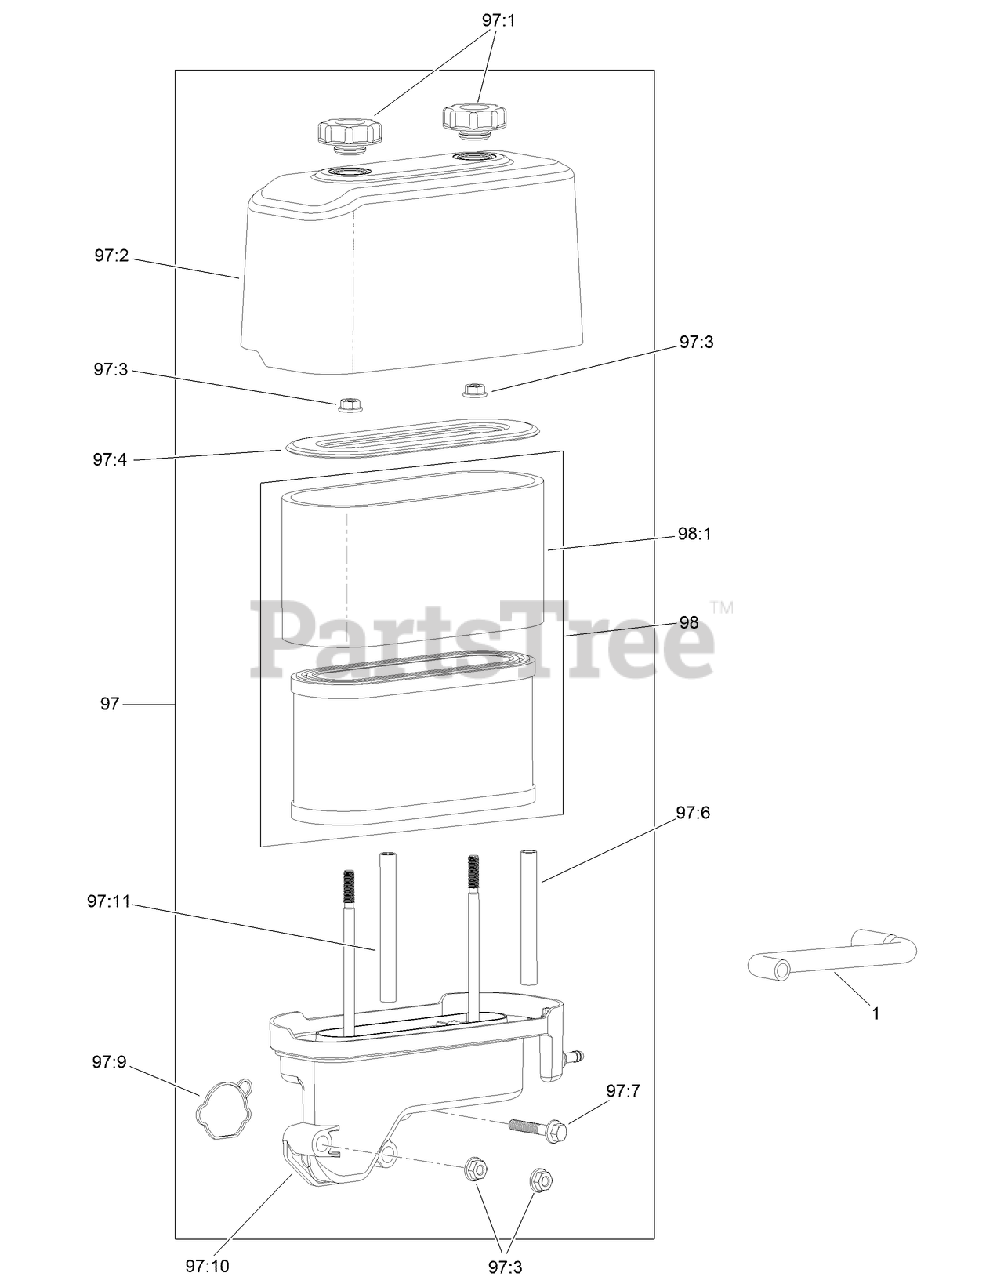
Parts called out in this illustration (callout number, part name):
1	TUBE-BREATHER
97:1	NUT-SPEED
97:2	COVER-FILTER, AIR
97:3	NUT-FLANGE
97:6	SPACER-FILTER, AIR
97:7	SCREW-HHF
97:9	GASKET-CARBURETOR
97:11	SPACER-FILTER, AIR
98:1	PREFILTER
